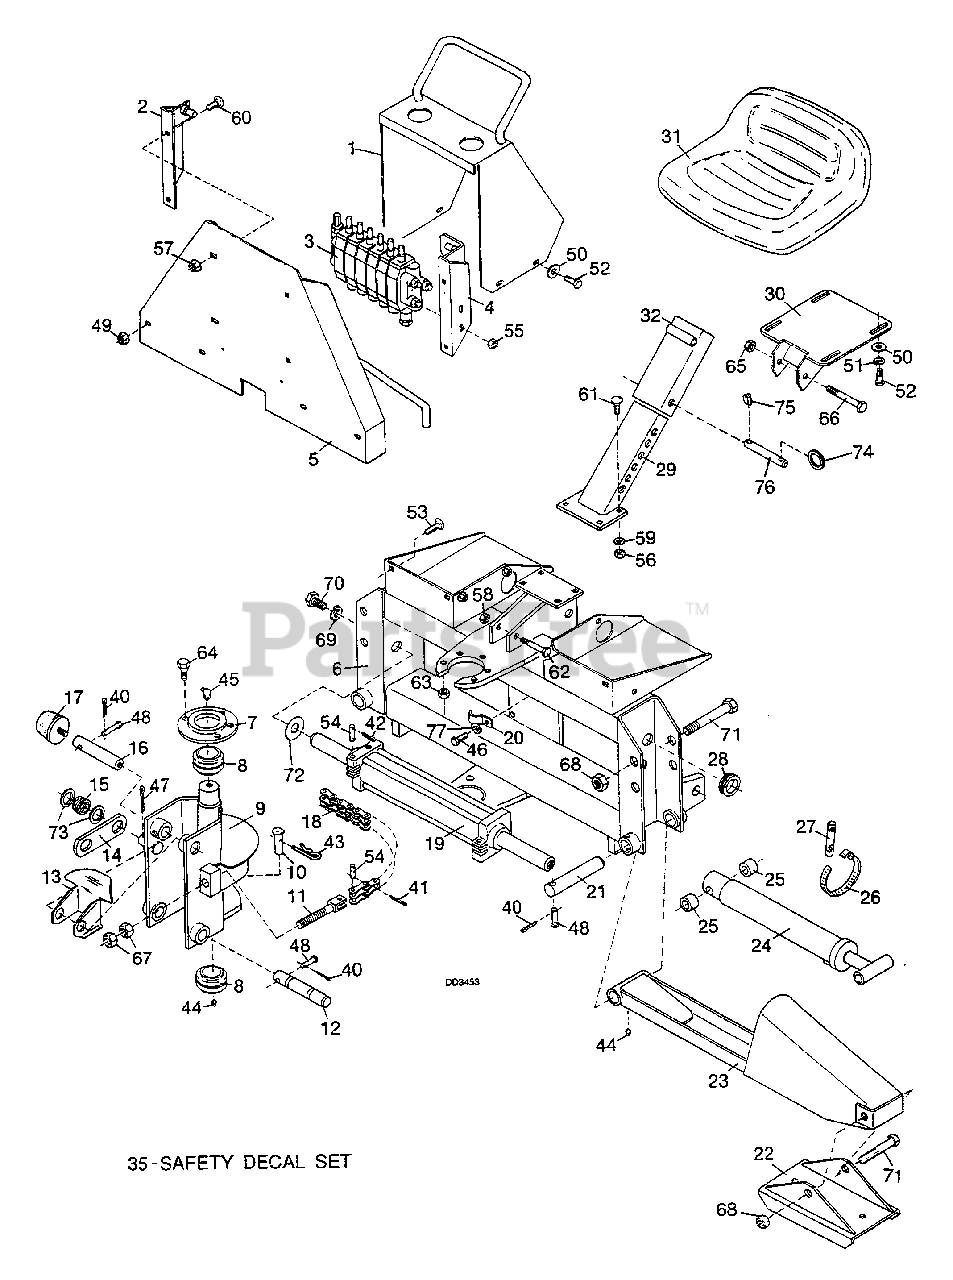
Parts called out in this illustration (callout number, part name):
1	Console cover
2	Right valve bracket assembly
3	Console valve
4	Left valve bracket assembly
5	Valve mounting plate assembly
6	Main frame assembly
7	Cap weldment assembly - Kingpost
8	1-1/2 ID Ball bushing
9	Kingpost weldment assembly
10	Swing lock pin, .5 x 2.75
11	Bolt - Chain tension
12	Pivot pin - 1 x 7.50 Boom
13	Guide - Hose
14	Plate - Latch
15	.072 x .62 Compression spring
16	Pin - 1 x 5.8 Pivot
17	Pad assembly - Bumper
18	Chain - Swing
19	Cylinder assembly - Hydraulic
20	Clamp - Hose
21	2 Pin - 1 x 6.5 Pivot
22	Pad weldment assembly - Stabilizer
23	Stabilizer weldment assembly
24	2 x 14-1/2 Hydraulic cylinder
25	13/16 x 1-1/4 x 1 Bushing
26	Hose clamp
27	Shield - Hose protector
28	Grommet - .25 x 1.0 x 1.38
29	Lower seat support
30	Seat bracket weldment assembly
32	Upper seat support
35	1 Safety decal set
40	1/16 x 1/2 Cotter pin
41	3/32 x 1/2 Cotter pin
42	3/32 x 1-1/2 Cotter pin
43	3/16 Safety pin
44	Straight 1/4 tapered thread grease fitting
45	1/4 - 28 Threaded 90° grease fitting
46	1/4 NC x 3/4 Hex head cap screw GR5
47	1/4 x 1-1/2 Cotter pin
48	1/4 x 1-7/8 Clevis pin
49	5/16 NC Flanged hex locknut
50	5/16 Standard flat washer
51	5/16 Standard flat washer
52	5/16 NC x 3/4 Hex head cap screw GR5
53	5/16 NC x 3/4 Carriage bolt
54	Pin - Chain
55	8mm x 1.25mm Pitch hex nut
56	3/8 NC Hex nut, plated
57	3/8 NC Flanged hex locknut
58	3/8 NC Hex locknut
59	3/8 Standard lockwasher
60	3/8 NC x 3/4 Carriage bolt
61	3/8 NC x 1 Carriage bolt GR5
62	3/8 NC x 3 Hex head cap screw GR5
63	7/16 NF Hex locknut
64	7/16 NF x 1-1/4 Wheel bolt GR5
65	1/2 NC Hex locknut
66	1/2 NC x 4 Hex head cap screw GR5
67	5/8 NC Hex nut
68	3/4 NC Hex locknut
69	3/4 Standard lockwasher
70	3/4 NC x 1-1/2 Hex head cap screw GR5
71	3/4 NC x 6 Hex head cap screw GR5
72	13/16 x .010 Shim washer
73	10 GA x 1 x 1-1/2 Washer
74	.11 x 1.1 OD Split ring
75	3/16 x 1 Klik pin
76	1/2 x 4-1/2 Clevis pin
77	1/4 Standard lockwasher
